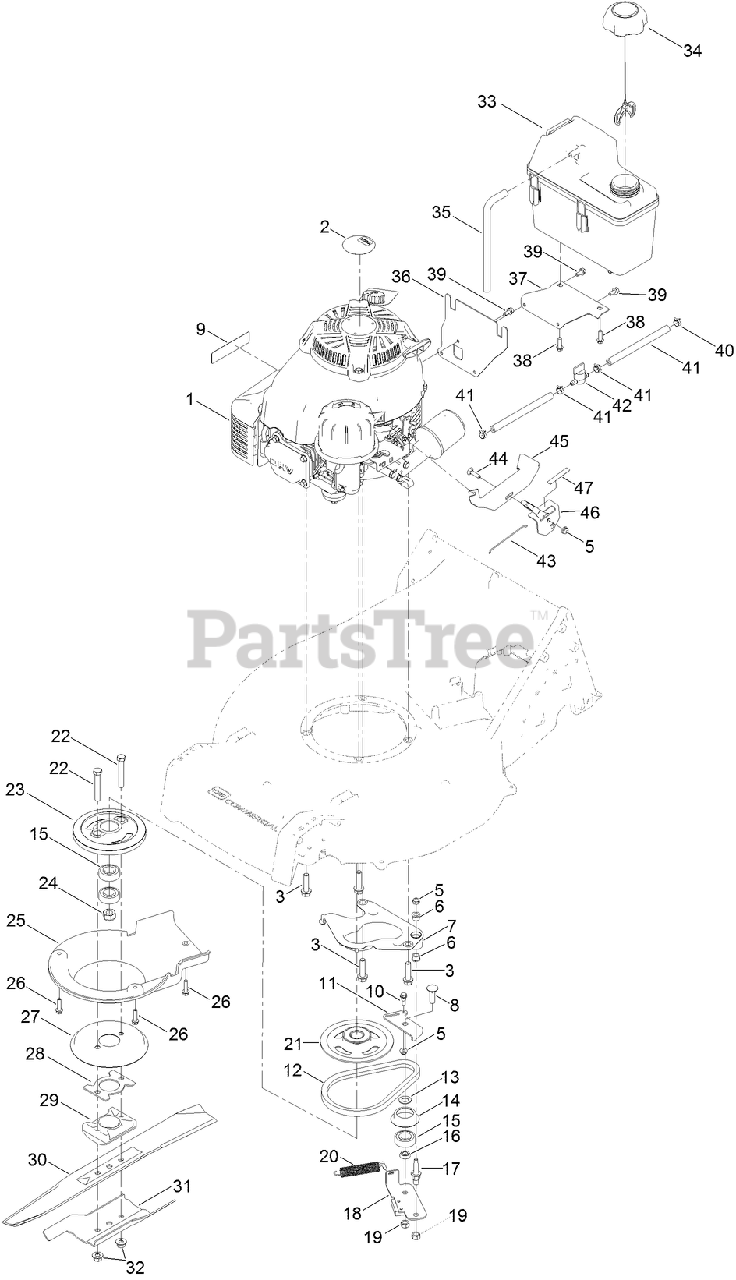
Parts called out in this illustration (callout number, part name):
3	SCREW-HWH
5	NUT-HF
6	BUSHING-FLANGE
7	PLATE-ANCHOR
8	BOLT-CARR
9	DECAL-ARRESTER, SPARK
10	BOLT-SHOULDER
11	PLATE-GUIDE, BBC
13	SPACER
14	RETAINER-BELT
15	BEARING-BALL
16	SPACER-BEARING
17	BOLT-SHOULDER
18	PLATE-BRAKE
19	NUT-HEX
20	SPRING-TENSION, BRAKE
21	PULLEY
22	SCREW-HH
24	NUT-HEX
26	SCREW-HWHTF
27	DISC
28	SPACER-DRIVER, BLADE
29	SUPPORT-BLADE
30	BLADE-RECYCLING
31	ACCELERATOR-BLADE
32	NUT-FLANGE, LOCK
33	TANK-FUEL
34	CAP-FUEL
35	HOSE-VENT, CANISTER
36	BRACKET-TANK, MOUNTING
37	BRACKET-TANK, SUPPORT
38	SCREW-HWH
39	SCREW-HWH
40	HOSE-FUEL
41	CLAMP-HOSE
42	VALVE-FUEL
43	WIRE-CONTROL
44	SCREW-CARR
45	BRACKET-MOUNT, THROTTLE
46	CONTROL-THROTTLE
47	DECAL-THROTTLE, CHOKE
